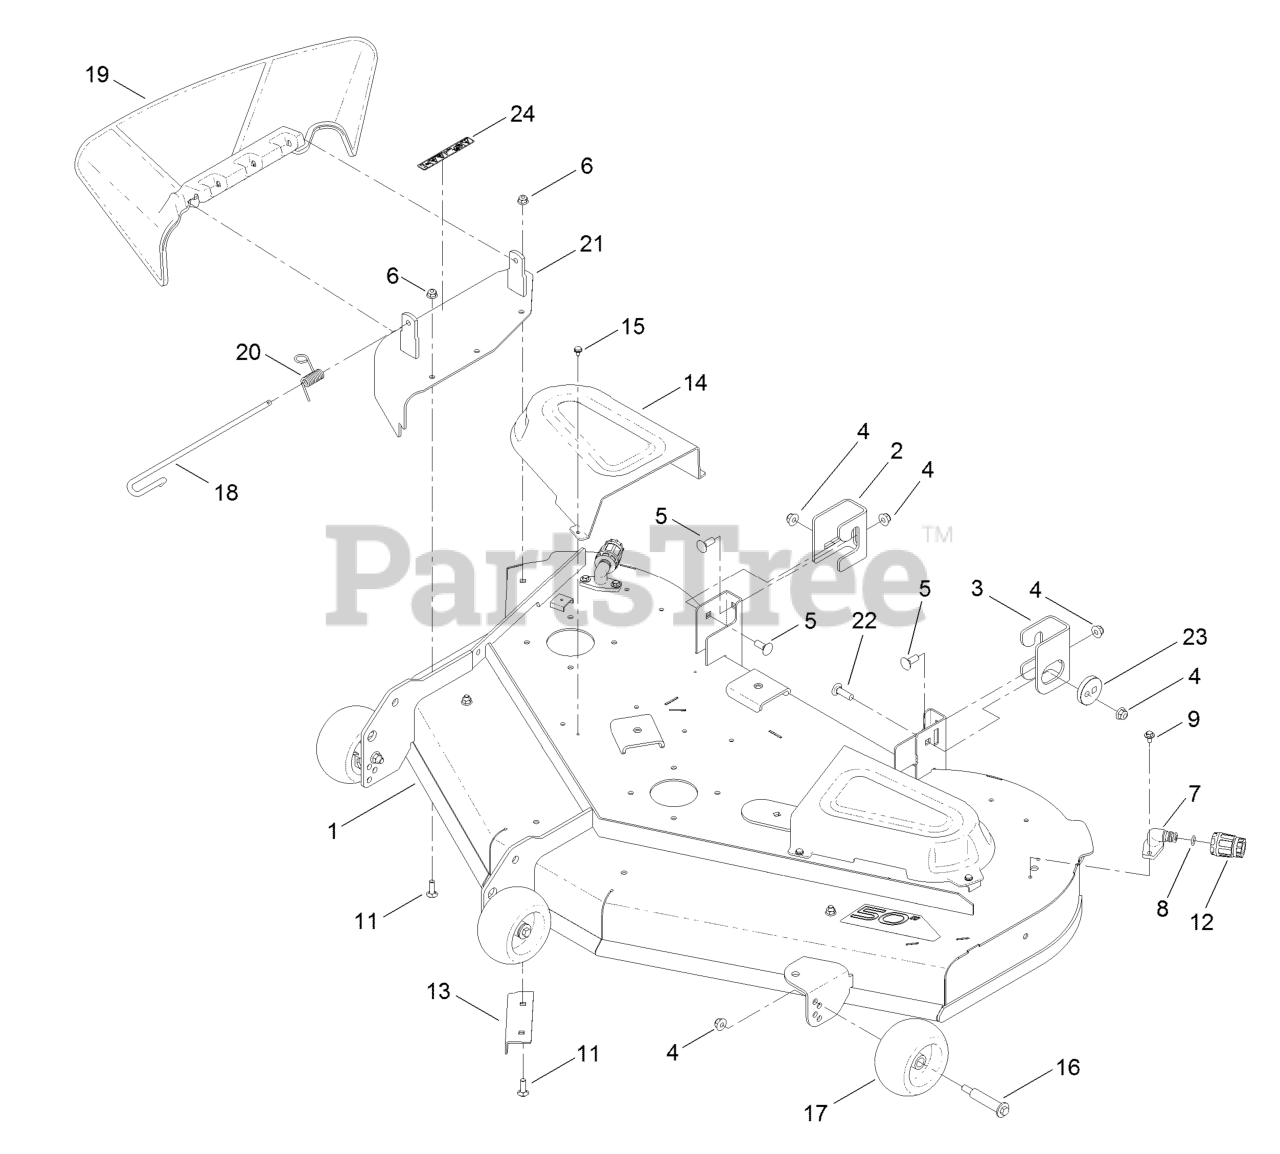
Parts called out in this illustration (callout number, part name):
1	50" DECK AND DECAL ASM (E
3	BRACKET-HANGER, LH
4	NUT-HF, NI
5	BOLT-CARR
6	NUT-HF, NI
9	SCREW-HHFTF
11	SCREW-CARR
12	CONNECTOR-HOSE
13	BAFFLE-CUTOFF
14	COVER-BELT
15	SCREW-TAPTITE
16	BOLT-SHOULDER
17	ROLLER-SCALP, ANTI
18	PIN-CHUTE
19	DEFLECTOR-DISCHARGE
20	SPRING-TORSION
21	COVER-DISCHARGE
22	Bolt-Carriage 3/8-16 X 1 1/4
23	ECCENTRIC
24	DECAL-DANGER
